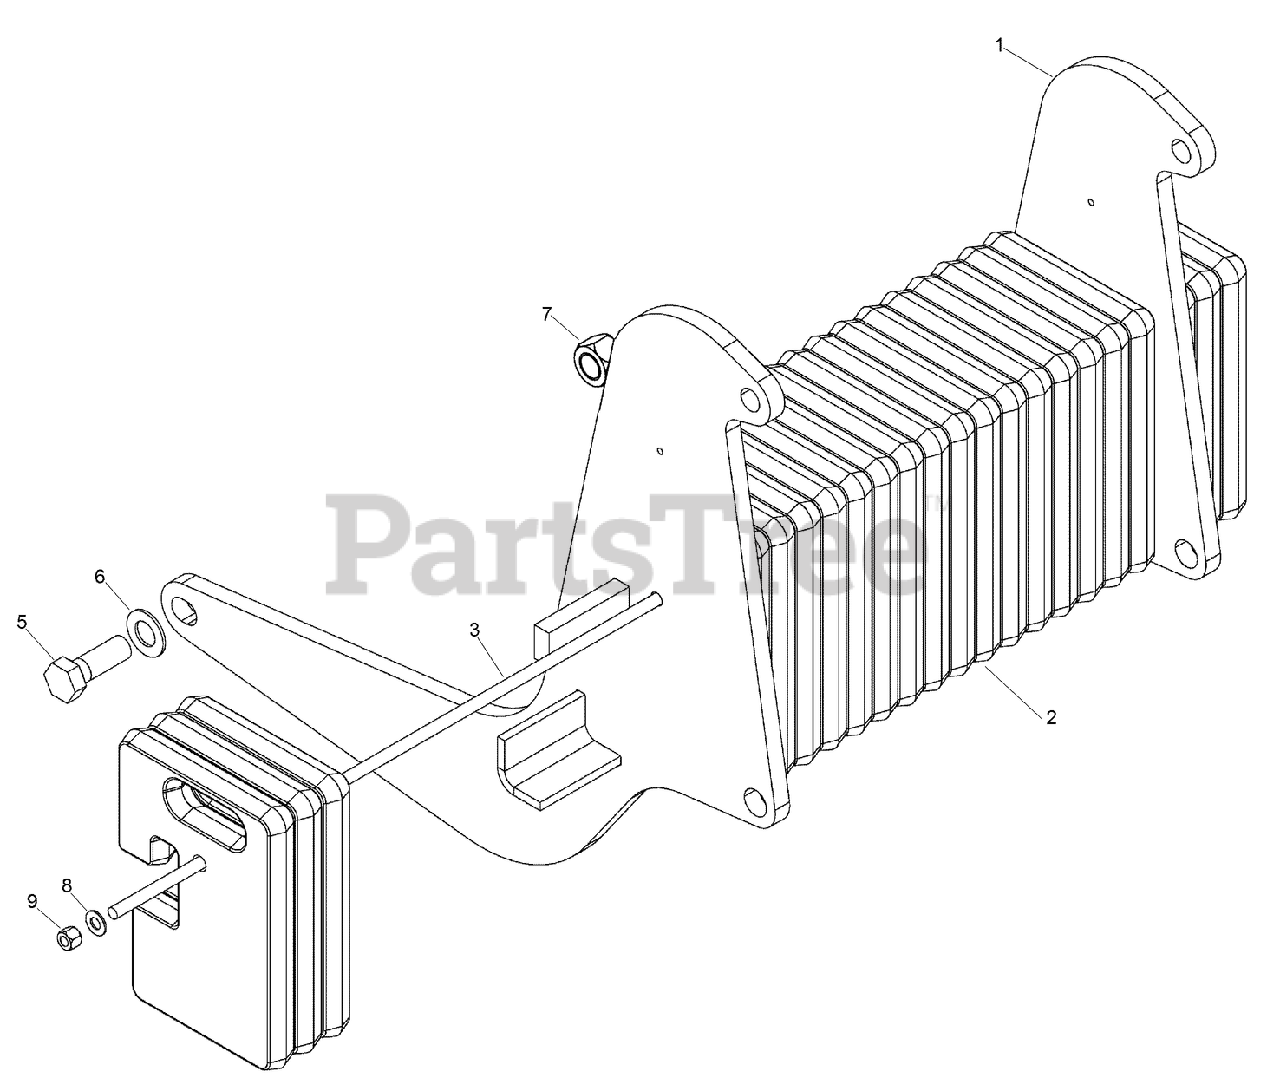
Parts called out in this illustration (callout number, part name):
1	FRAME WELDMENT - Reel Carrier Mtg
2	COUNTERWEIGHT-60lb
3	ROD-WEIGHT
8	WASHER-FLAT
9	NUT-LOCK, HEX
